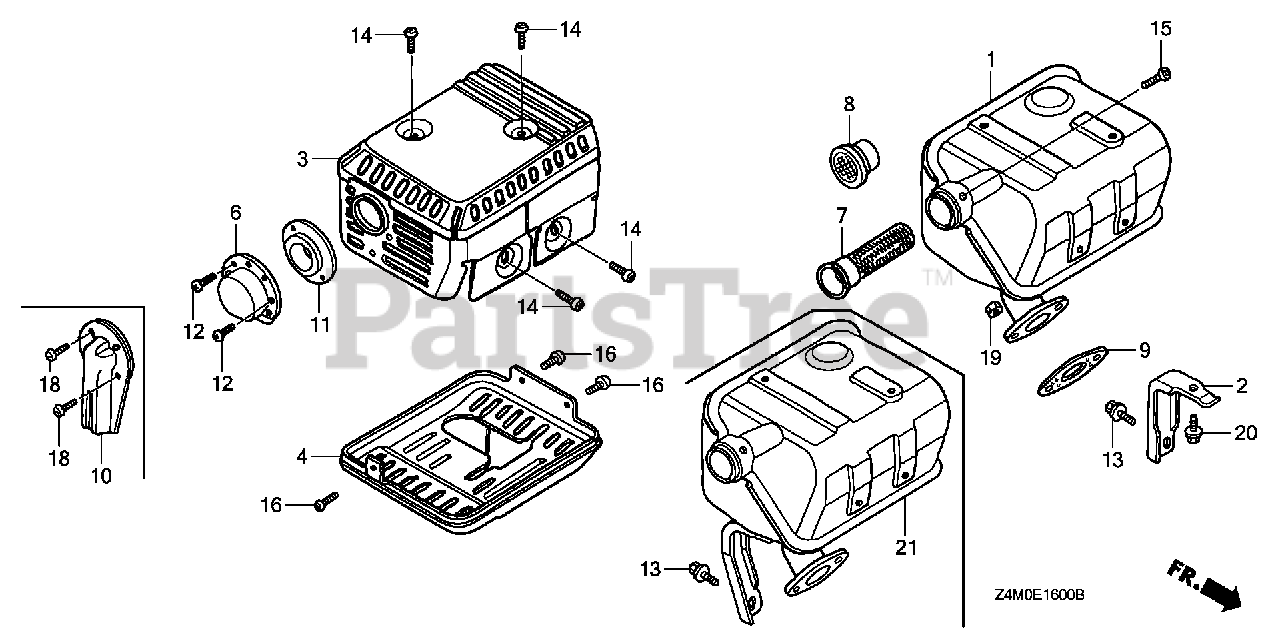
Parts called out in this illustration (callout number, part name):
1	MUFFLER (ARRESTER) (SPARK ARRESTER TYPE)
3	PROTECTOR, MUFFLER (STD) (BLACK)
6	DEFLECTOR
7	ARRESTER, SPARK
9	GASKET, MUFFLER
11	GUIDE, MUFFLER
12	SCREW, TAPPING (4X8)
14	SCREW, TAPPING (5X8)
15	SCREW, TAPPING (4X6) (TO INSTALL OPTIONAL SPARK ARRESTER)
19	NUT, HEX. (8MM)
